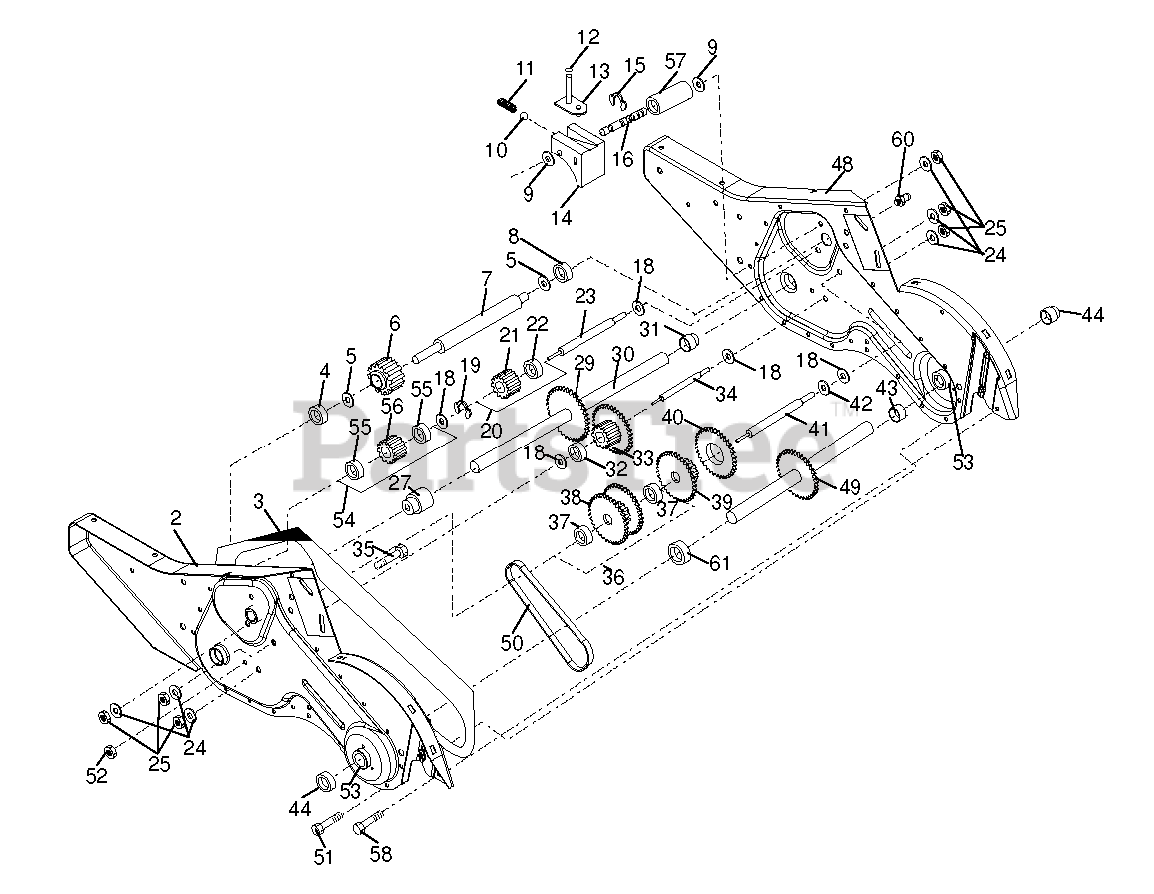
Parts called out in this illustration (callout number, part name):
2	GEARCASE.ASM.DRT.LH.
3	GASKET.GEARCASE.CRT/DRT.
4	NEEDLE BRNG LT
5	THRUST WASHER
6	PINION INPUT DRT TILLER
7	SHAFT.INPUT.D.9TEETH
9	WASHER, SEAL (2 2)
10	BALL, STEEL
11	SPRING-SHIFT CRT
13	BRACKET ASM.SHIFT.CRT
14	SHIFT FORK TI
16	SHAFT.SHIFT.DRT
20	GEAR ASSY CRT
21	GEAR-REV IDLR CRT
22	NEEDLE BEARING TI
23	SHAFT.IDLER.REVERSE.CRT
24	LOCKWASHER
25	NUT.ASF.HEX.7/16
27	BEARING.GROUND.DRIVE
30	GROUND SHAFT ASS'Y
31	BEARING, SHAFT RH CRT
33	SPRCKT 8 GEAR CRT
34	SHAFT.SECONDARY.REDUCTION.CRT
35	SCRW WHIZ LOK CRT
36	GEAR & SPROCKET.ASM.WBEARIN
37	NEEDLE BEARING
38	ASM.GEAR & SPROCKET
39	GEAR.CLUSTER.DRT.TILLER
41	SHAFT.REDUCTION.FIRST.DRT
42	BRNG RACE T
44	SEAL ASM, OIL
48	GEARCASE.ASM.DRT.RH.
49	SHAFT.ASM.TINE
50	CHAIN.TILLER
51	SCREW
53	KIT.BEARING.TILLER.
54	GEAR.ASM.DRT.TILLER
55	DRAWN CUP ROLLER BEARING W/CAG
56	GEAR.DRT.IDLER
57	SPACER.SPLIT
58	BOLT SHOULDER 1/4-20 UNC X.875
60	FITTING.GREASE.TAPERED
61	SPACER.1.015X1.50X.650
